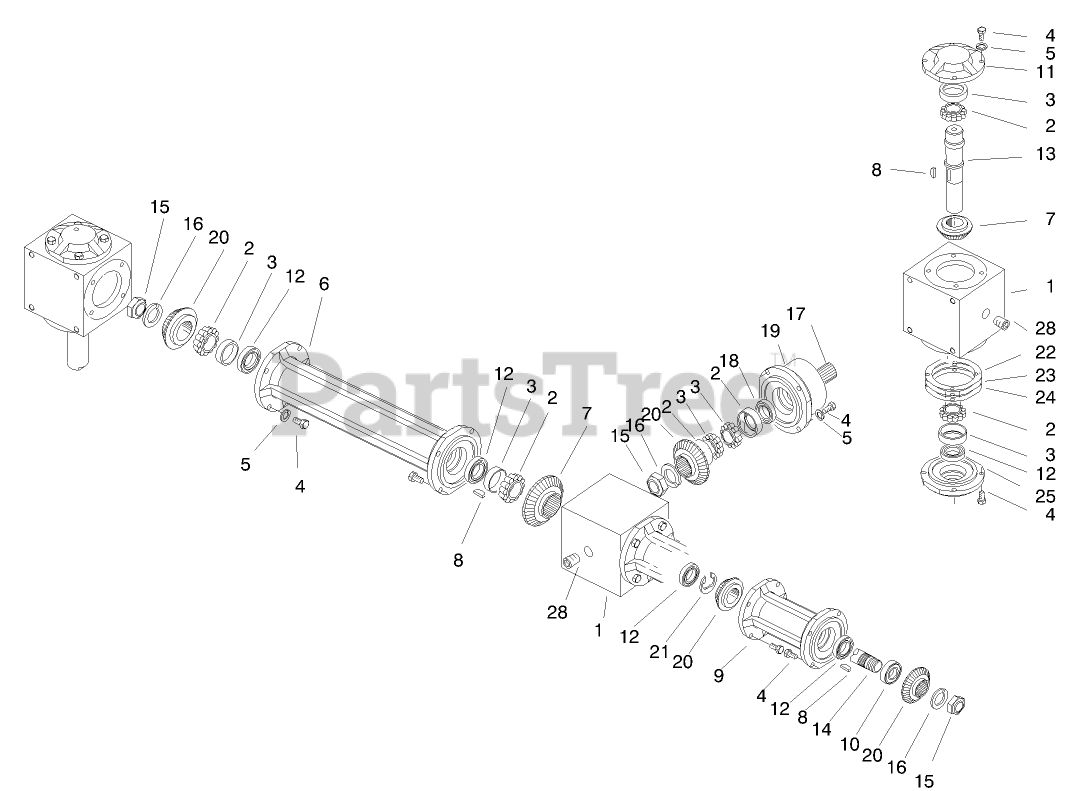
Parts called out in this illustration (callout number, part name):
1	HOUSING
2	BEARING - CONE
3	Cup
4	SCREW - HH
5	WASHER - LOCK
6	Connector-Hub
7	Gear-RH
9	Connector-Hub
10	BEARING - BALL
11	CAP - BLANK
12	Seal
13	Shaft-Thru
14	SHAFT
15	NUT - LOCK
16	WASHER - LOCK
17	SHAFT - HUB
20	PINION - LH
21	RING - RETAINING
22	Gasket-.015
23	Gasket-.005
24	GASKET - .003
25	CAP - THRU
26	I.d. Tag
27	I.d. Tag Cover
28	PLUG (OBS, C/R TO 281-10)
